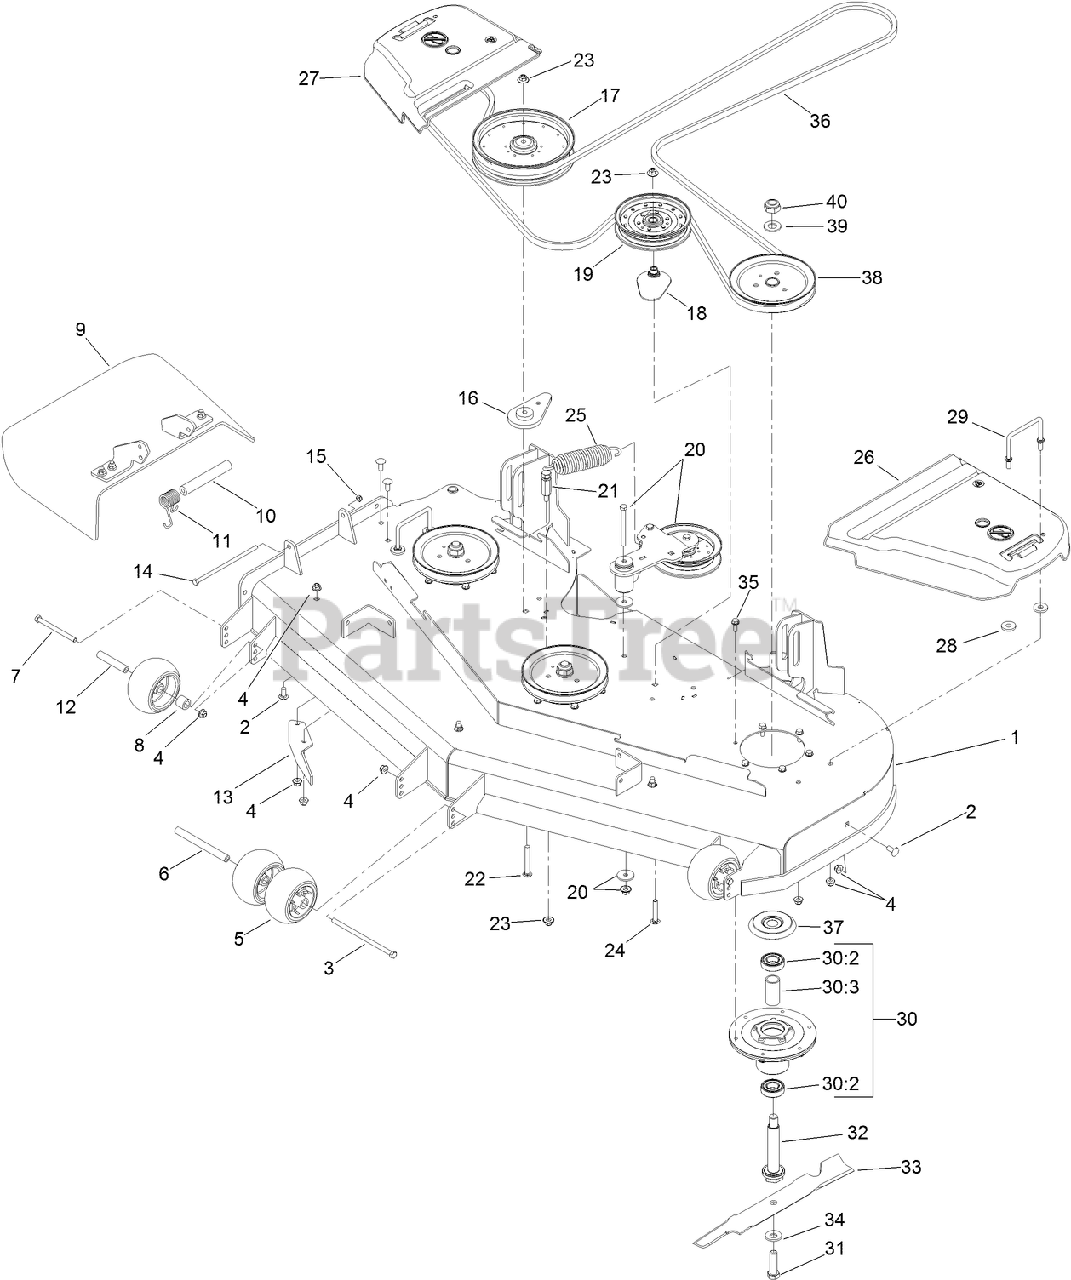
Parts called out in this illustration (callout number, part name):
1	DECK DECAL ASM
2	SCREW-CARR
3	SCREW-HH
4	NUT-HF, NI
5	ROLLER-SCALP, ANTI
6	SPACER-WHEEL
7	SCREW-HH
8	TUBE-SPACER
9	DEFLECTOR ASM
10	SPACER
11	SPRING-TORSION
12	TUBE-SPANNER
13	BAFFLE-DISCHARGE
14	SCREW-HH
15	NUT-LOCK, NI
16	SPACER-IDLER
17	PULLEY-IDLER
18	SPACER-PULLEY
19	PULLEY-IDLER, FLAT
20	IDLER ARM ASM
21	ANCHOR-SPRING, TALL
22	SCREW-CARR
23	NUT-FLANGE, NI
24	BOLT-CARR, SHORT NECK
25	SPRING-EXTENSION
26	COVER-BELT, LH
27	COVER-BELT, RH
28	WASHER
29	WIREFORM-COVER
30	SPINDLE ASM
30:2	BEARING-BALL
30:3	SPACER-BEARING
31	SCREW-BLADE
32	SPINDLE-SHAFT
33	BLADE-HI FLOW, 20.5 INCH
34	WASHER-BELLEVILLE
35	SCREW-TAPTITE
36	BELT-V
37	SHIELD-BEARING
38	PULLEY B SECTION
39	WASHER
40	NUT-LOCK, NI
